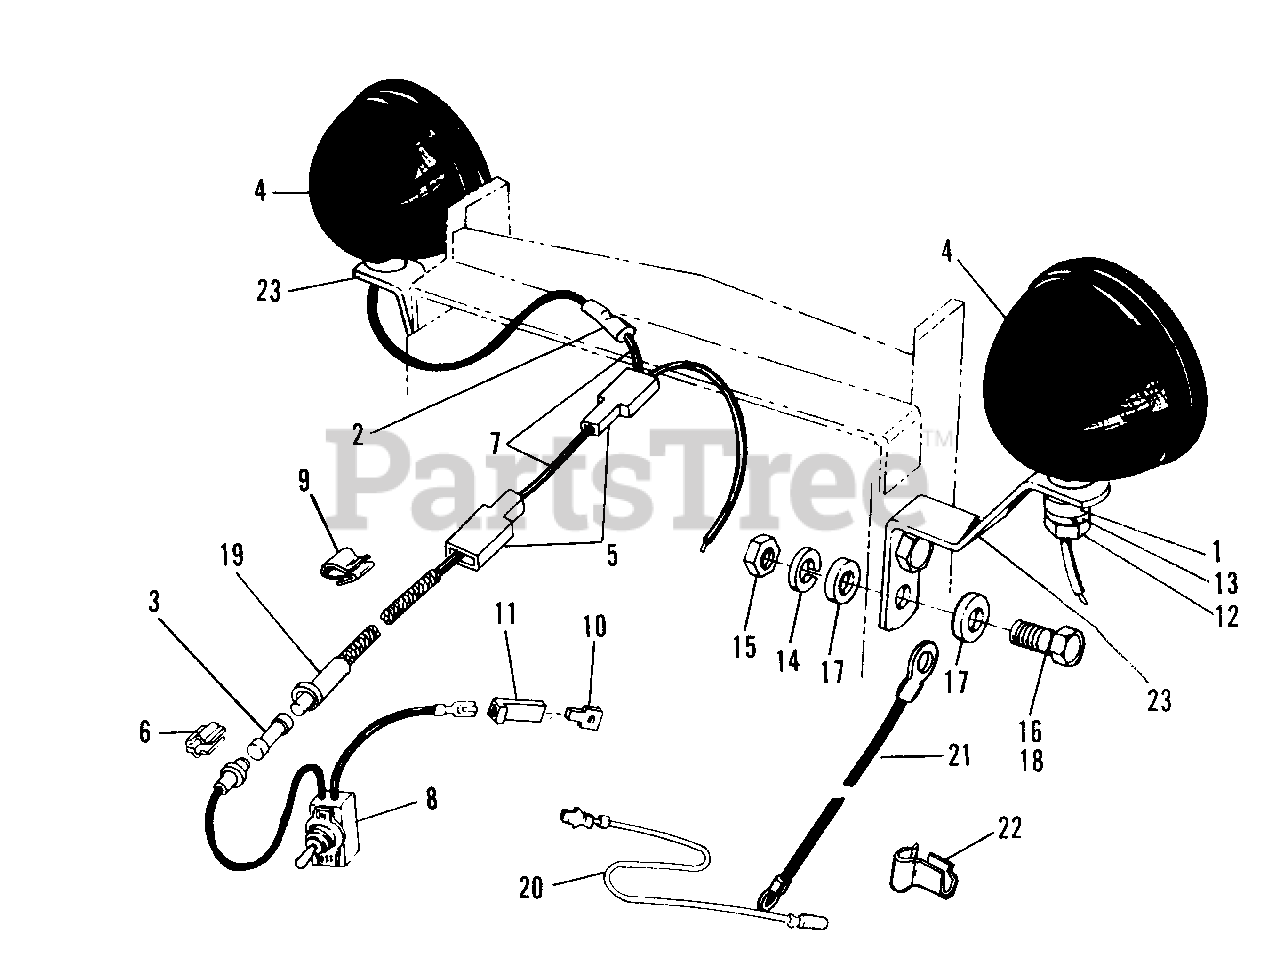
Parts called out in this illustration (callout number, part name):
2	CONNECTOR
3	FUSE, 20 AMP
4	LAMP ASSEMBLY
5	CONNECTOR, Insulated
6	CLIP, Fuse
7	WIRE, Extension
8	SWITCH, Toggle
9	CLIP, Speed
11	CONNECTOR, Insulated
12	NUT, Hex, full, 1/2-13
13	LOCKWASHER, 1/2
14	LOCKWASHER, 5/16
15	NUT, full Hex, 5/16-18
16	CAPSCREW, Hex, 5/16-18 x 3/4
17	WASHER, Plain, 5/16
18	CAPSCREW, Hex, 5/16-18 x 1-1/2
20	WIRE, Lead
22	CLIP, Wire
23	BRACKET, Head light
